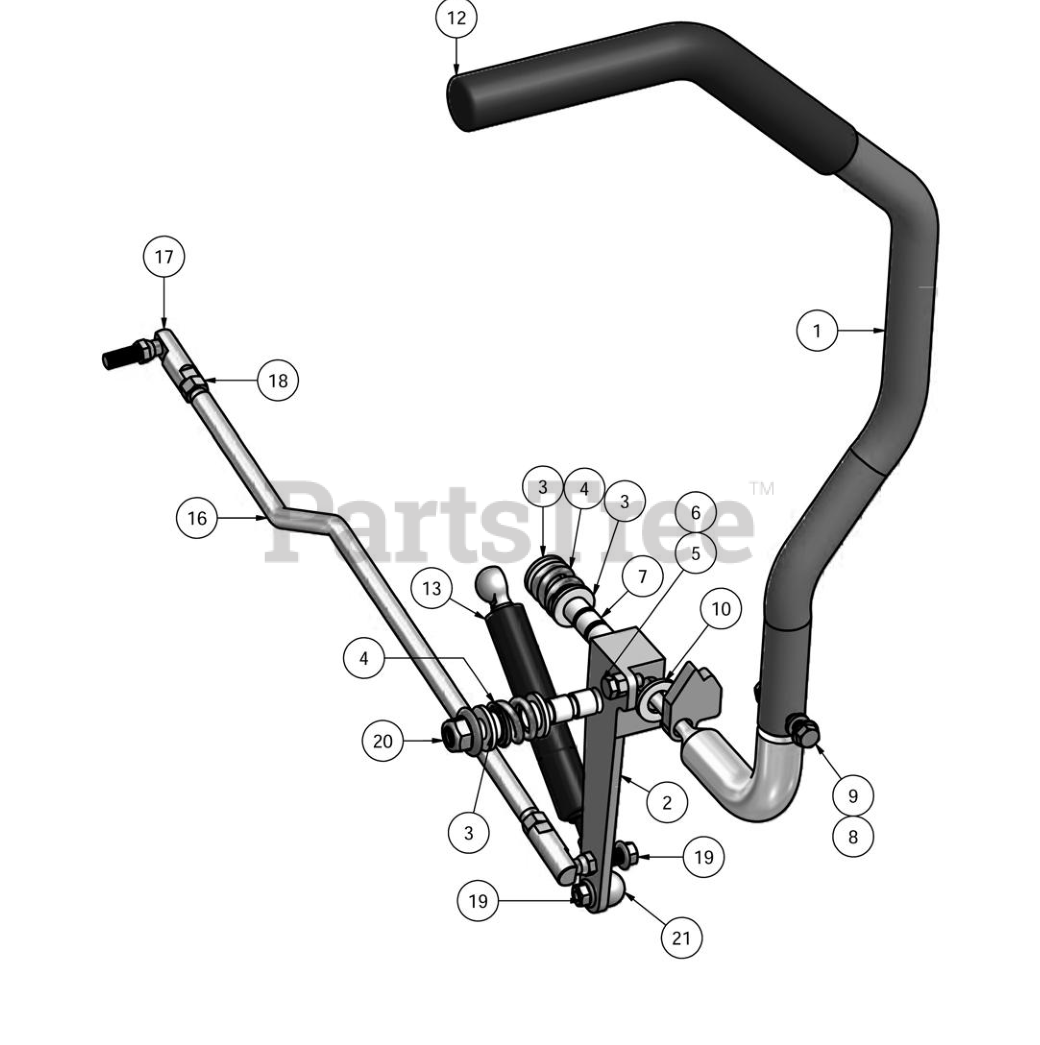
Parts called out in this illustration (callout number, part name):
1	Drive Arm (Left)
1A	Drive Arm (Right)
2	Drive Arm Lever Housing (Left)
2A	Drive Arm Lever Housing (Right)
3	.515 ID Nylon Shoulder Washer
4	Drive Lever Spring
5	5/16" x 3/4" Hex Bolt
7	.507 ID Nylon Bushing
8	5/16" Lock Washer
9	5/16" x 1/2" Flange Bolt
10	.505 ID Plastic Washer
12	Rubber Grip
17	3/8-24 Ball Joint
18	3/8" Fine Threaded Jam Nut
19	5/16" Flange Nut
20	1/2-13 Nylon Flange Nut-Orange
21	10MM Damper Ball Stud
